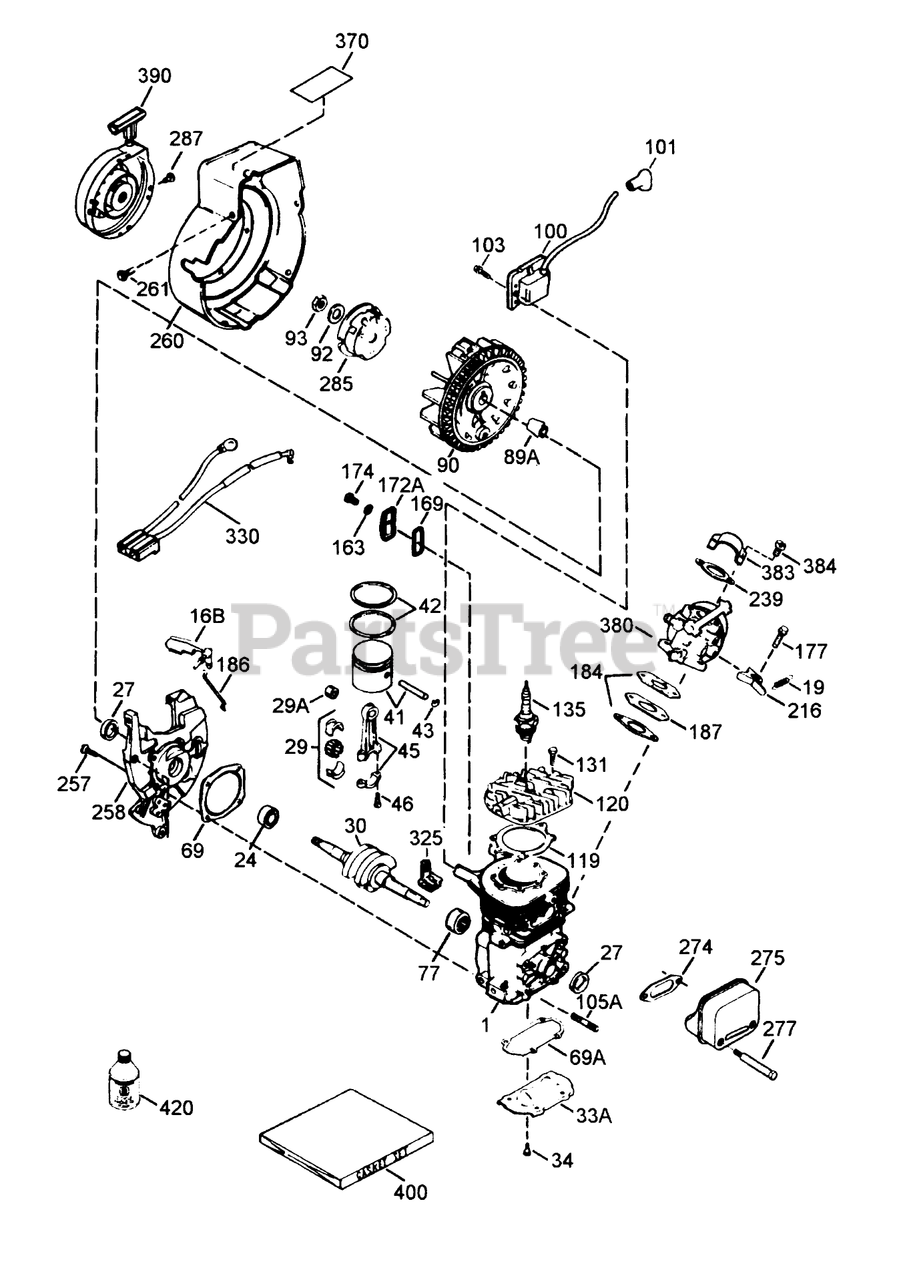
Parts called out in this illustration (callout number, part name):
1	Block Ass-y-Cylinder (Order short block if replacement is required)
16B	Vane-Air
19	Spring-Extention
24	Bearing-Ball
27	Seal-Oil
29	Needle Bearing and Liner Set (37 Needles)
29A	Bearing-Cartridge
30	Crankshaft
33A	Plate-Cover
34	Screw (T-25, 10-24 x 1/2)
41	Piston (Incl. Ref. #43)
42	Ring Set
43	Ring-Retaning
45	Rod Assy.-Connecting (Incl. Ref. #3, 3A 3B)
46	Bolt-Rod, Connecting
69	Gasket-Cover, Cylinder
69A	Gasket-Plate, Cover
77	Bearing-Cartridge
89A	Blade (20 inch)
90	CARB BODY S
92	Washer-Belleville
93	Nut-Flywheel
100	Solid State
101	Cover-Spark Plug
103	Screw
119	Gasket-Head, Cylinder
120	Head-Cylinder
131	Screw (T-30, 1/4-20 x 3/4)
135	Spark Plug-Resistor (R C J 8Y)
163	Washer
169	Cover-Compression, Release
172A	Cover-Release, Compression
174	Screw (T-25, 10-24 x 1/2)
177	Screw (5/32 Allen, 1/4-20 x 1)
184	Gasket-Carburetor
186	Governor-Link
187	Spacer
216	Lever-Adjusting, Rpm
239	2060A77 WIZARD ROTA
257	Screw (T-30, 1/4-20 x 5/8)
258	Base Ass-y-Blower Housing (Incl Ref. #20)
260	Housing-Blower
261	Screw (1/4-20 x 1/2)
274	Gasket-Exhaust
275	Muffler (Incl. Ref. #274 277)
277	Screw (1/4-20 x 2-3/4)
285	Cup-Starter
287	Screw (8-32 x 21/64)
325A	Clip-Wire
330	Harness-Wire
370	Decal-Warning
380	Carburetor (Incl. Ref. #184A)
383	Baffle-Carburetor
384	Screw
390	Rewind Starter
400	Gasket Set
420	2-Cycle Oil (8oz)
